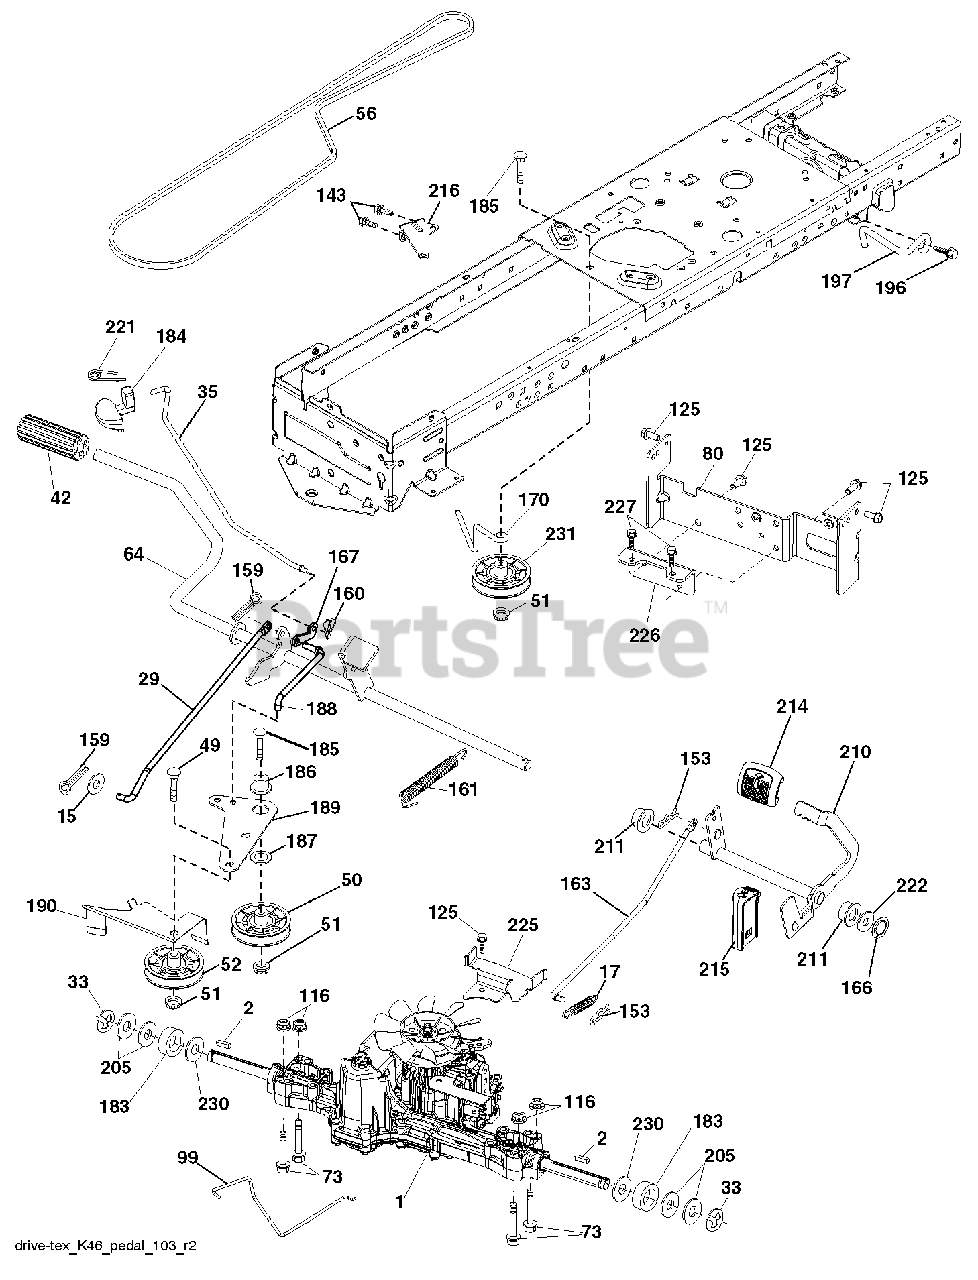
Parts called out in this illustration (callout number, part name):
2	SQUARE KEY
15	WASHER
17	SPRING.BRAKE.K46.GREEN
29	ROD.BRAKE.K46
35	ROD.CNTRL.PARK.PREDATOR.LT.TEX
42	PEDAL COVER T
50	IDLER.FLAT.910.OFFSET
51	NUT LOCK FLG 3/8-16 UNC
52	IDLER.V-GROOVE.910.OFFSET
56	V-BELT.MOWER.92.40.42/K46
64	SHAFT.ASM.PEDAL.BRK.CNTR
80	STRAP.TORQUE.K46.K57R.TT
99	ROD.SPRING.BYPASS.K46.LT.Z
116	NUT LOCK HEX FLANGE 5/16-18
125	SCREW
143	SCREW LT
153	RETAINER M
159	COTTER PIN
160	RETAINER CLIP
161	SPRING, RETURN LT
163	ROD.CONTROL.K57R.K46
166	NUT.PUSH.625
167	LATCH.BRAKE.SPRING
170	KEEPER.CENTER SPAN.1.688
183	SPACER AXLE
184	HANDLE.PARKING.BRK.PRED.LT.RED
186	SPACER.RETAINER
187	WASHER 12/32X2X10GA
188	RP LINK.CLUTCH.GROUND.DRIVE
189	BELLCRANK.GROUND.DRIVE.TEX.
190	KEEPER.BELLCRANK.DRIVE
196	SCREW 3/8-16X1
197	LINK.CLUTCH.ANIT-ROTAT
210	ROCKER.ASM.PEDAL.CONTR
211	BEARING.NYLON
214	PEDAL.FORWARD.PAD.TEX
215	PEDAL.REVERSE.TEX.GT.4
216	BRACKET.PULLEY.IDLER.W/TEX
221	RETAINER.SPRING.CLIP.H
222	WASHER 21/32 X 1-1/4 X 10 GA.
225	KEEPER.BELT.TRANSAXLE.K46
226	BRACKET.MOUNT.TORQUE.K46.TLT
227	SCREW
230	WASHER.HARDENED
231	IDLER.V-GROOVE.1.688.OFFSET
